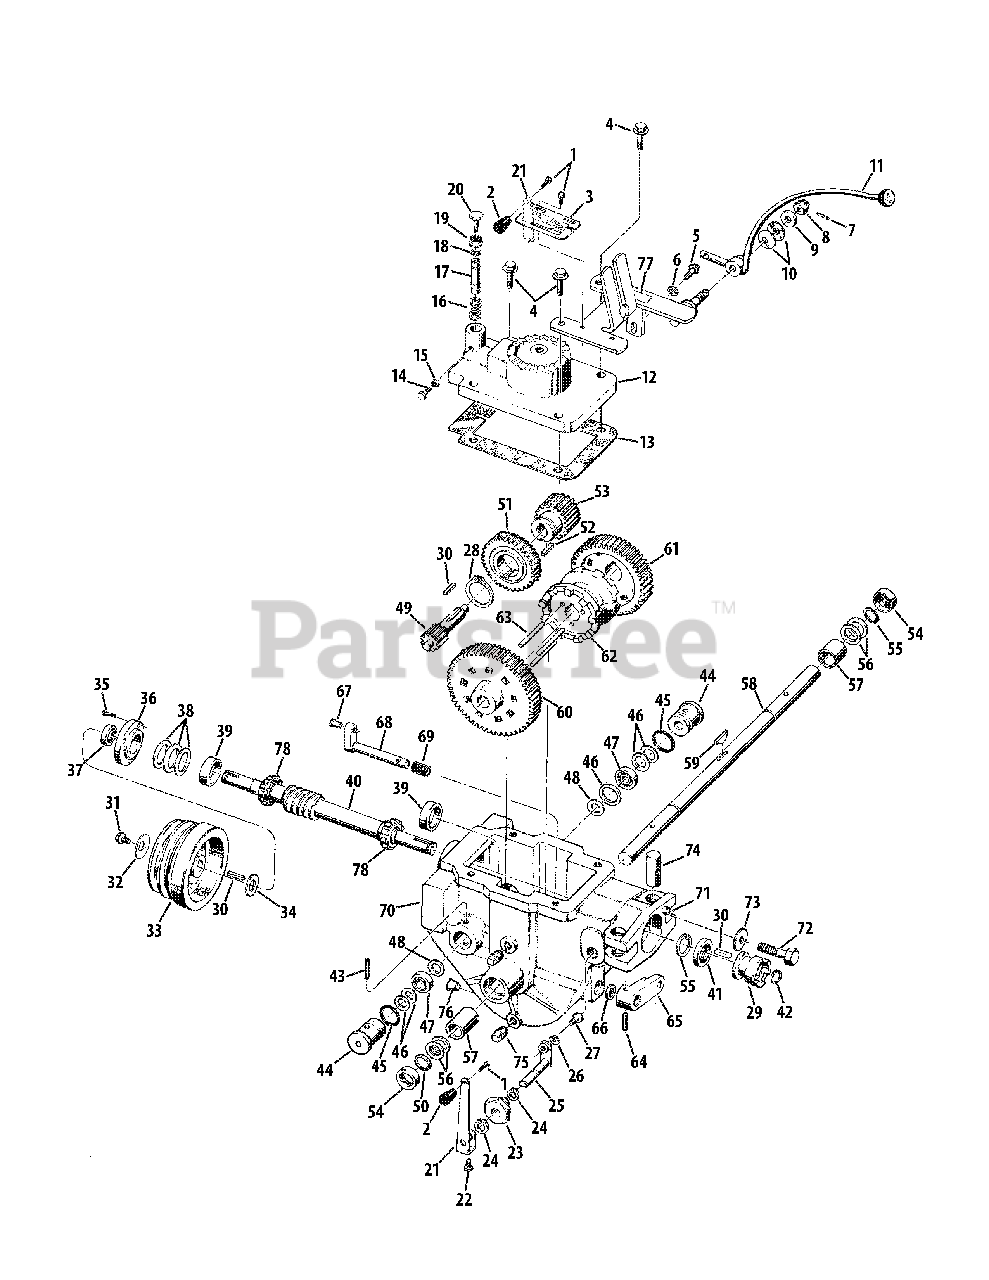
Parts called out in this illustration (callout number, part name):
1	Hex Head Screw, #10-32 x 3/8"
4	Hex Flange Bolt, 3/8-16 x 1-1/2"
5	Hex Flange Bolt, 5/16-18 x 3/4"
6	Flat Washer, 5/16"
7	Spring Pin, 1/8"
8	Hex Nut, 1/2-20
9	Shoulder Washer, 1/25 x .50 x .25
10	Disc Spring Washer, 1.97 x 1.0 x .118
11	Wheel Speed Shift Lever
12	Power Unit Transmission Cover
13	Transmission Cover Gasket
14	Hex Head Screw, 5/16-18 x 1"
15	Hex Nut, 5/16"-18
16	Plunger Spring
18	Clip Ring
19	Flange Lock Nut, 3/8-16
20	Screw, 3/8-16x1-1/2"
21	Tines/PTO Clutch Lever
22	Hex Head Screw, 1/4-20 x 1/2"
23	Tines/PTO Clutch Bushing
24	External Retaining Ring
25	Tines/PTO Clutch Shaft
26	Hi-Collar Lockwasher, 1/4"
27	Socket Head Screw, 1/4-20 x 3/8"
28	External Retaining Ring
29	Dog Clutch
30	Key, 3/16 x 1"
31	Hex Head Screw, 5/16-24 x 3/4"
32	Spring Washer, .827 x .331 x .098
33	Transmission Drive Pulley
34	Flat Washer, 1/25 x .687 x .075
35	Flange Nut, 1/4-20 x .75
36	Front Bearing Cap
38	Flat Washer, 1.175 x 1.5 x .062
38	Flat Washer, 1.175 x 1.5 x .005
38	Flat Washer, 1.175 x 1.5 x .03
38	Flat Washer, 1.175 x 1.5 x .01
39	Cup Bearing
40	Main Drive Shaft
42	Retaining Ring
43	Roll Pin (Spirol), 1/4 x 2
44	Pinion Bearing
46	Flat Washer, 1/234 x 1.015 x .062
46	Flat Washer, 1/234 x 1.015 x .033
46	Flat Washer, 1/234 x 1.015 x .01
47	Ball Bearing
48	Washer
49	Pinion Stem
50	External Retaining Ring, 1.387 ID
51	Worm Gear
52	Key, 3/16" x 5.8"
53	Fast Speed Pinion Gear
55	External Retaining Ring
56	Flat Washer, 1.375 x 1.015 x .005
56	Flat Washer, 1.375 x 1.015 x .01
56	Flat Washer, 1.375 x 1.015 x .015
56	Flat Washer, 1.375 x 1.015 x .03
56	Flat Washer, 1.375 x 1.015 x .062
57	Bushing, 1.25 x 1.005 x 1.5
58	Wheel Shaft
59	Hi-Pro Key, .250 x 1.8125
60	Slow Speed Gear
61	Faste Gear Speed
62	Dog Clutch
63	Clutch Guide Pin, 1/4"
64	Spring Pin, 3/16" x 1-1/4"
65	Wheel Speed Shifting Lever
67	Wheel Speed Shifting Pin
68	Wheel Speed Shifting Shaft
70	Transmission Housing
71	Alignment Pin
72	Hex Screw, 1/2-13 x 2"
73	Disc Spring Washer
75	Pipe Plug, 1/4"
76	Plug.Red Plastic
77	Clutch Bracket
78	Cone Bearing
